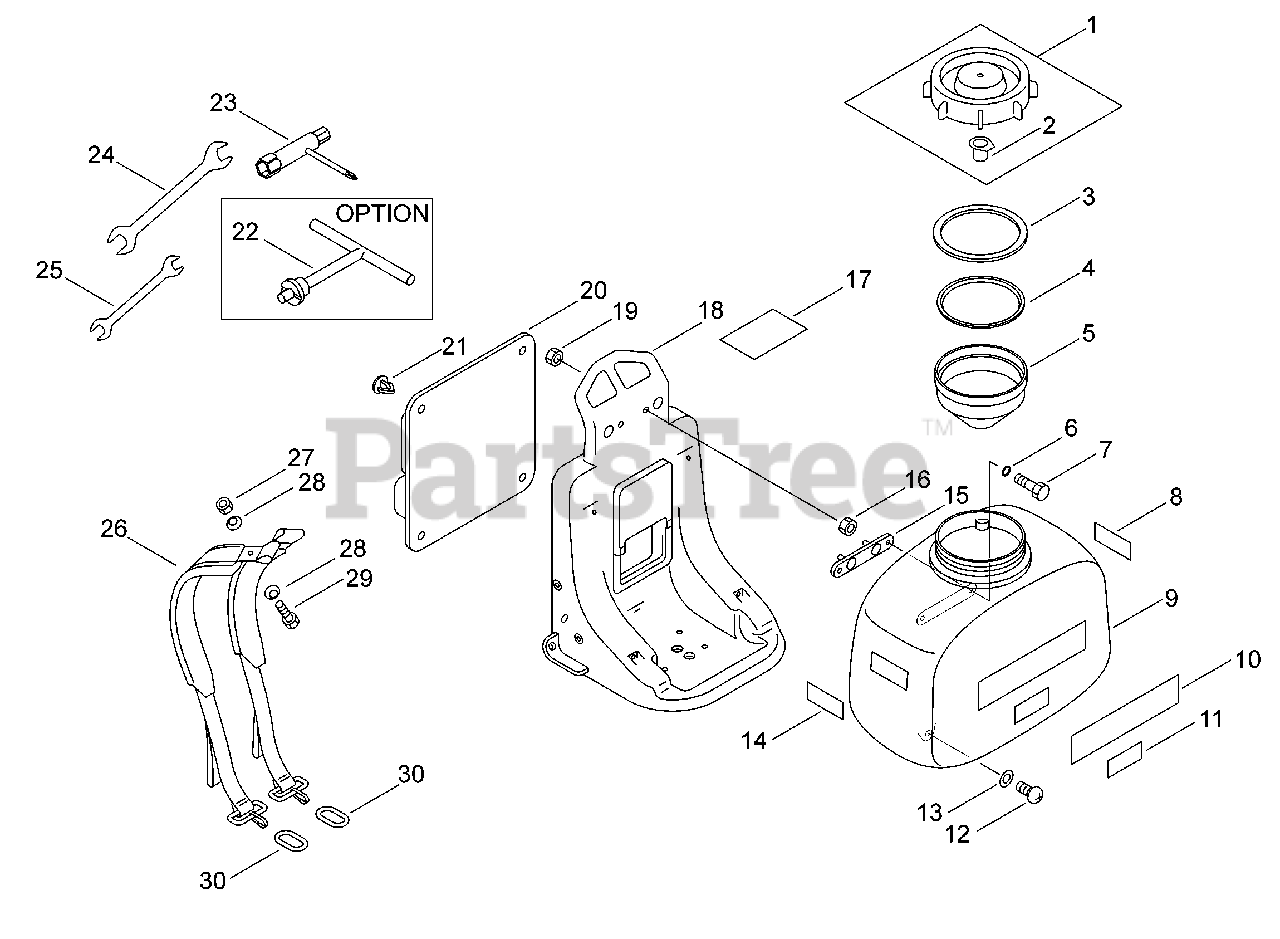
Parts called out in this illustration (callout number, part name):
1	CAP, CHEMICAL TANK
2	BREATHER
3	GASKET, CHEMICAL TANK
5	FILTER, TANK
6	O-RING P-10A
8	LABEL, CAUTION L-E
8	LABEL, CAUTION
9	TANK, CHEMICAL
10	LABEL, ECHO
11	LABEL, MODEL
12	SCREW, TAPPING
14	LABEL, CAUTION
15	BRACKET, TANK
16	NUT, FLANGE 6
17	BAG, POLY
18	FRAME ASSY, BACKPACK
19	NUT, FLANGE 6
20	CUSHION, BACKPACK
22	TOOL, DRIVER
23	T-WRENCH
24	SPANNER 14×17
25	SPANNER 10×12
26	HARNESS, BACKPACK
27	NUT, LOCK M5
29	SCREW 5×14
30	RING, HARNESS
